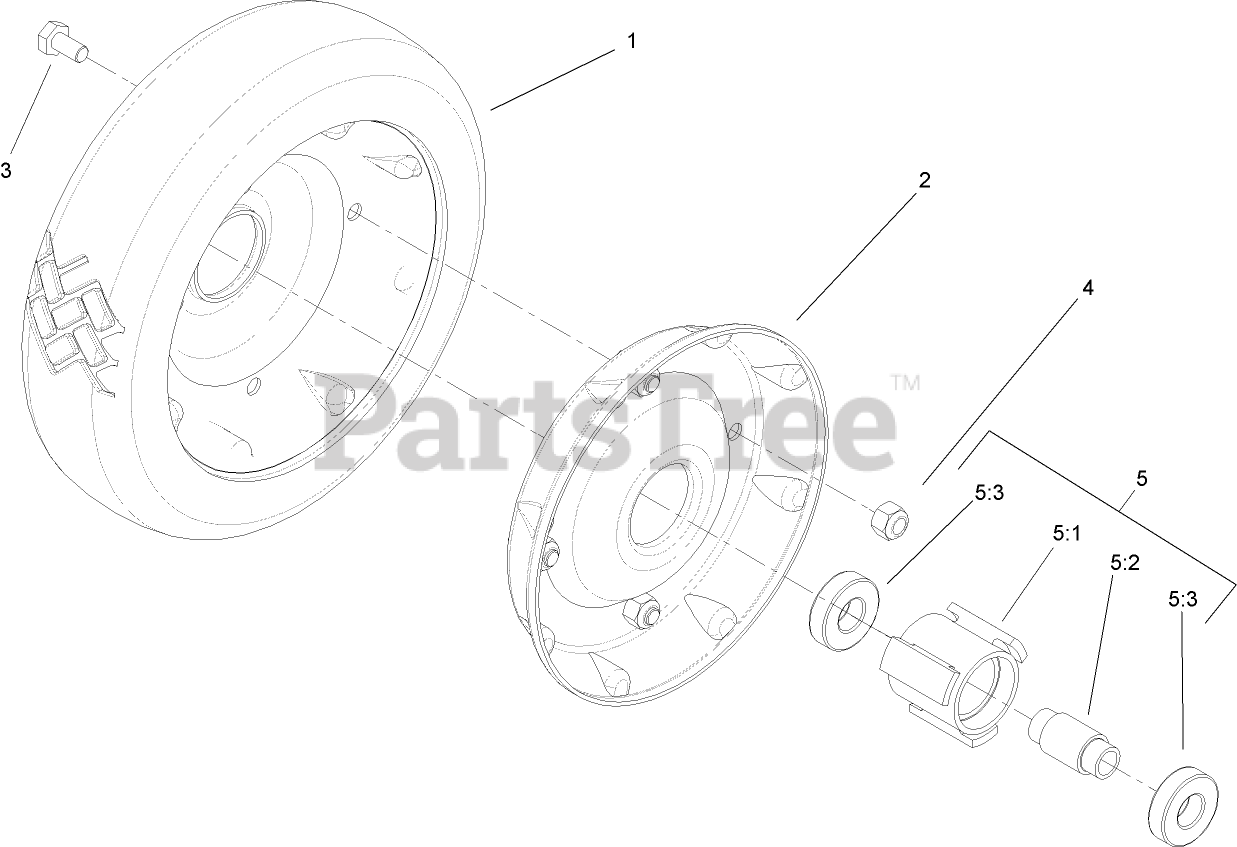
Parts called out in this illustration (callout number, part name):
3	SCREW-HH
4	NUT-LOCK, NI
5	Loose Parts Package
5:1	HUB-BEARING
5:2	SPACER-BEARING
5:3	BEARING-WHEEL
